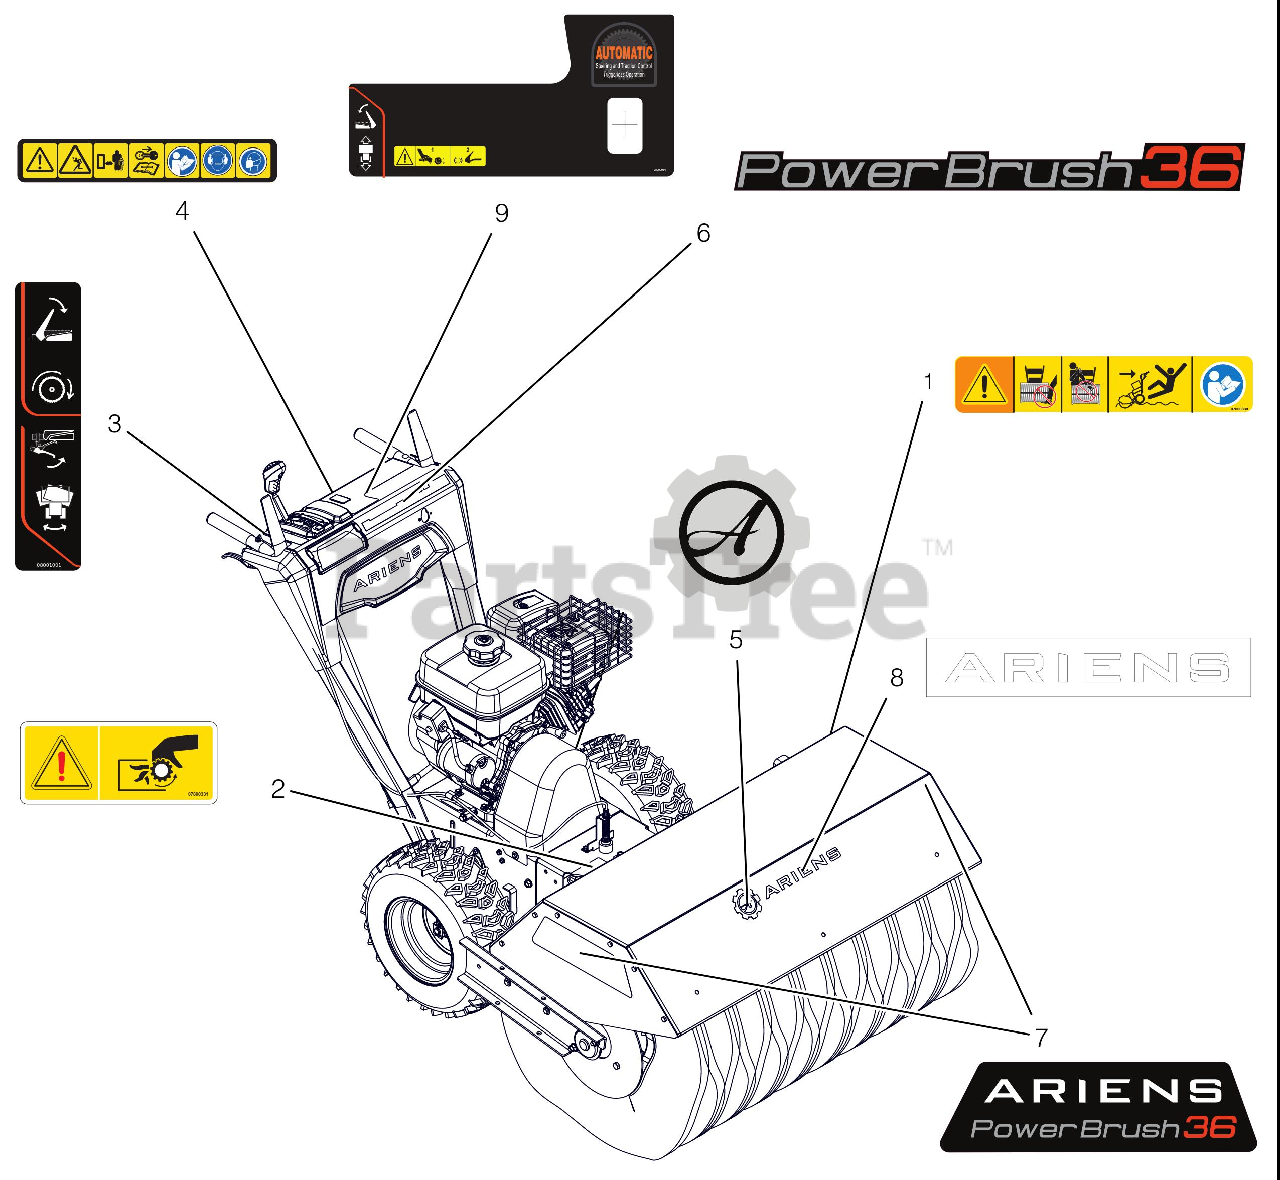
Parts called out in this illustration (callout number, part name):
1	DECAL, DANGER -POWER BRUSH-CE
2	DECAL, PTO WARNING
3	DECAL,CONTROL,BRUSH,RH
4	DECAL, SAFETY, DASH, BRUSH
5	DECAL, ARIENS-GEAR BADGE
6	DECAL, DASH - PB 36 FRICTION
7	DECAL - ARIENS PB 36 FRICTION
8	DECAL - ARIENS 9.625"
9	DECAL,CNTRL,LRG BRUSH,LH,FRCTN
